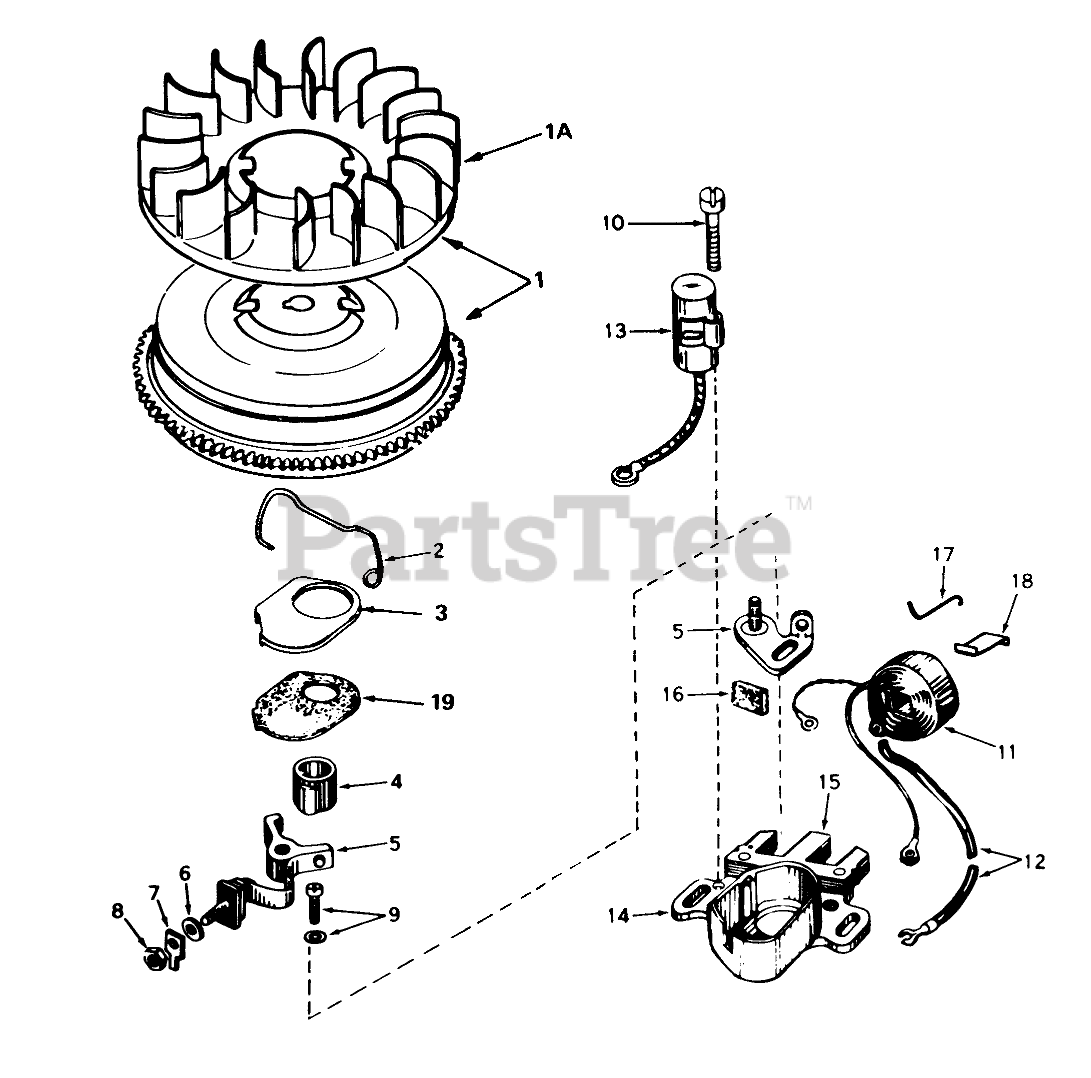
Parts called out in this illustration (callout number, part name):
1	Flywheel (Incl. Ref. #1A)
1A	Fan
2	Spring Breaker Box
3	Cover-Dust
4	Cam-Breaker
5	Breaker Assy.
6	Washer
7	Terminal, Ground
8	DECAL
9	Breaker Screw
10	Condenser Screw
11	Coil Assy. (Incl. Ref. #12)
12	Wire, Lead
13	Condenser
14	Core & Plate
15	Stator Assy. (Incl. Ref. #2, 3, 5 thru 14 & 16 thru 19)
16	Felt,Cam Wiper
17	Clip, Coil
18	Spring Coil Wedge
19	Gasket-Dust Cover
